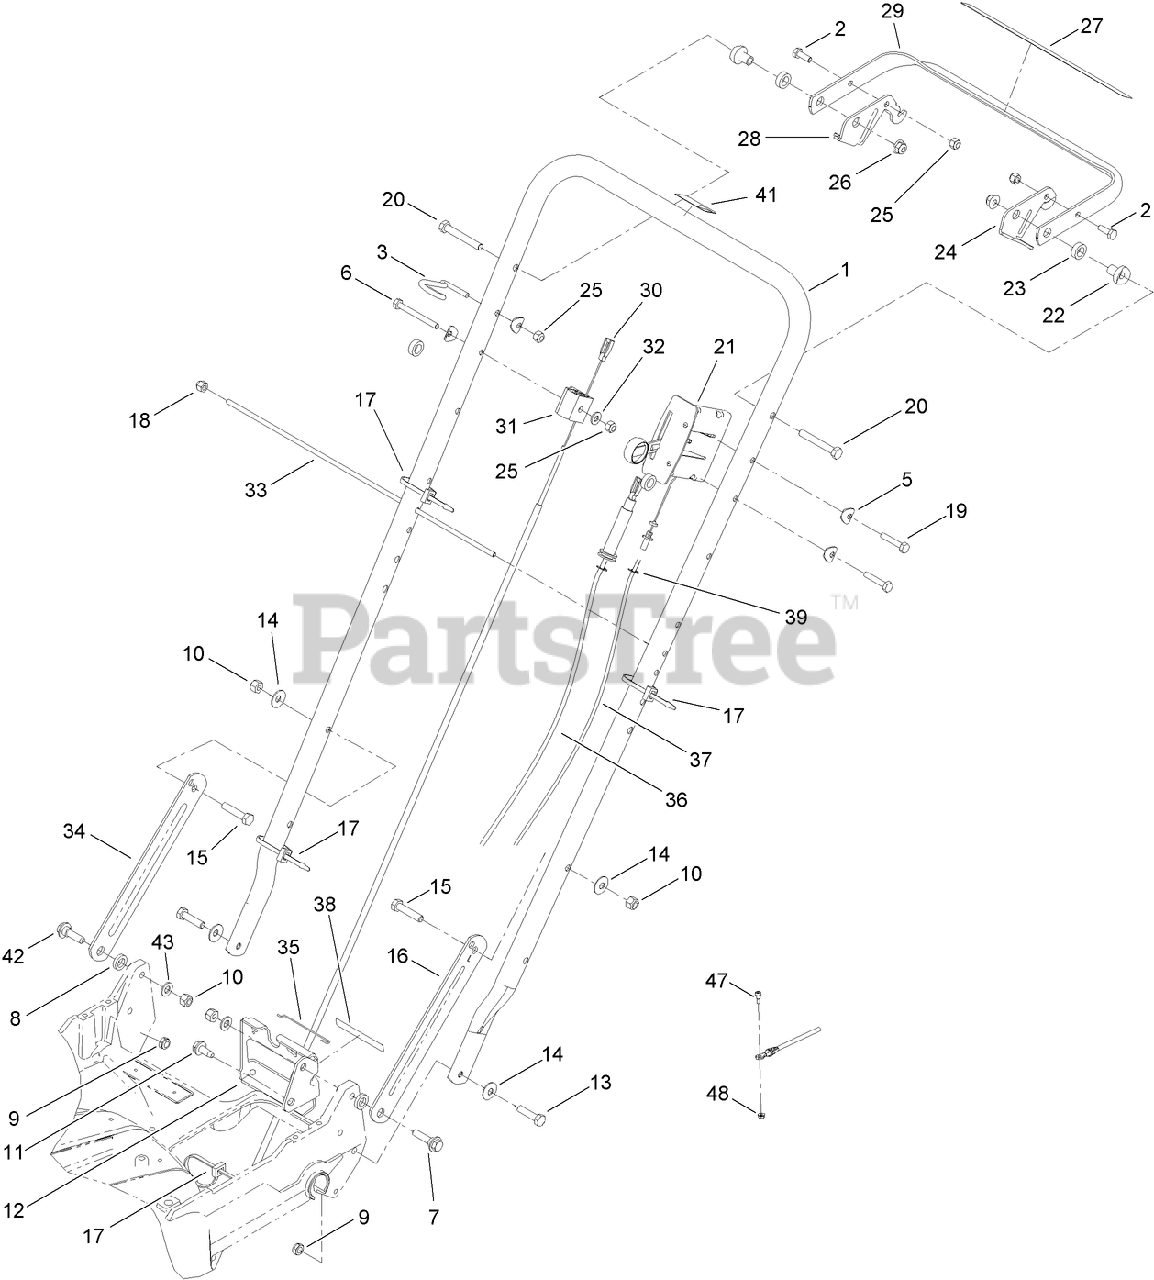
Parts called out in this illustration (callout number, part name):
2	SCREW-HH
3	GUIDE-ROPE
5	WASHER
6	SCREW-HH
7	SCREW-SHOULDER
8	SPACER
9	NUT-LOCK, NI
10	NUT-LOCK, NI
11	SCREW-HWHTF
12	BRACKET-ADJUSTMENT, TRACTION
13	SCREW-HH
14	WASHER-BELLEVILLE
15	SCREW-HH
16	LATCH-HANDLE, LH
17	TIE-CABLE
18	NUT-CAP
19	SCREW-HH
20	SCREW-HH
21	CONTROL-HEAD, THROTTLE
22	SPACER-SUPPORT
23	SPACER-NYLON
24	LEVER-CONTROL
25	NUT-LOCK, NI
26	NUT-HF, NI
27	DECAL-TRACTION
28	LEVER-CONTROL
29	BAR-CONTROL
30	CABLE-BRAKE, CONTROL
31	SUPPORT-CABLE
32	WASHER-FLAT
33	ROD-SUPPORT, BAG
34	LATCH-HANDLE, RH
35	RETAINER-CABLE
36	CABLE-TRACTION
37	THROTTLE CABLE ASM
38	DECAL-POSITION, GEAR
39	E-RING
41	DECAL-PROTECTION, EAR
42	SCREW-SHOULDER
43	WASHER-PLAIN
47	SCREW-SHOULDER
48	NUT-LOCK, FLANGE
